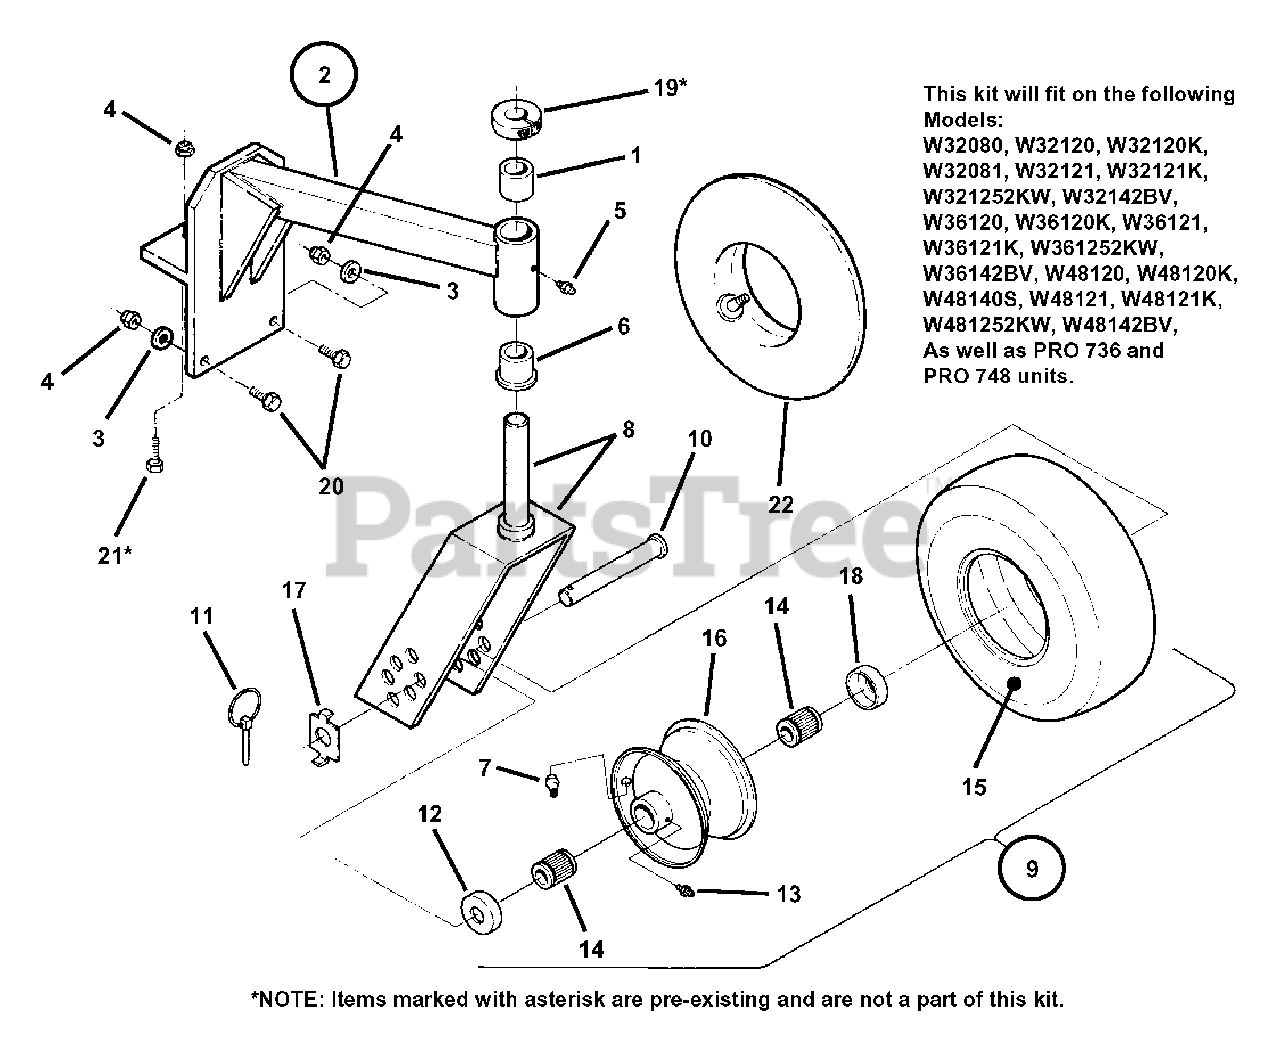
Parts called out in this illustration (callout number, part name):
1	BUSHING, Straight
2	SUPPORT, Caster w/Bushings (7-6514 & 7-6515) (2)
3	WASHER, 3/8" Flat
4	NUT, 3/8-16 Hex Nyloc
5	FITTING, Lube, 1/8 NPT Straight
6	BEARING, Flange Thrust (powdered metal)
7	STEM, Air Valve
8	YOKE, Caster (weldment)
9	ASSEMBLY, Pneumatic Tire
10	AXLE, Caster
11	LYNCH PIN, 3/16" Diameter
12	CAP, End
13	FITTING, Lube, 1/4-28, Straight
14	BEARING, Roller
15	TIRE, Pneumatic
16	RIM, Pneumatic Tire
17	WASHER, Tab
18	CAP, End
19	COLLAR, Clamp 7/8" (existing)
20	SCREW, 3/8-16 x 1" Hex Head Cap
21	BOLT, 3/8-16 x 1-3/4" Hex Head Cap (existing)
22	TUBE, Inner
